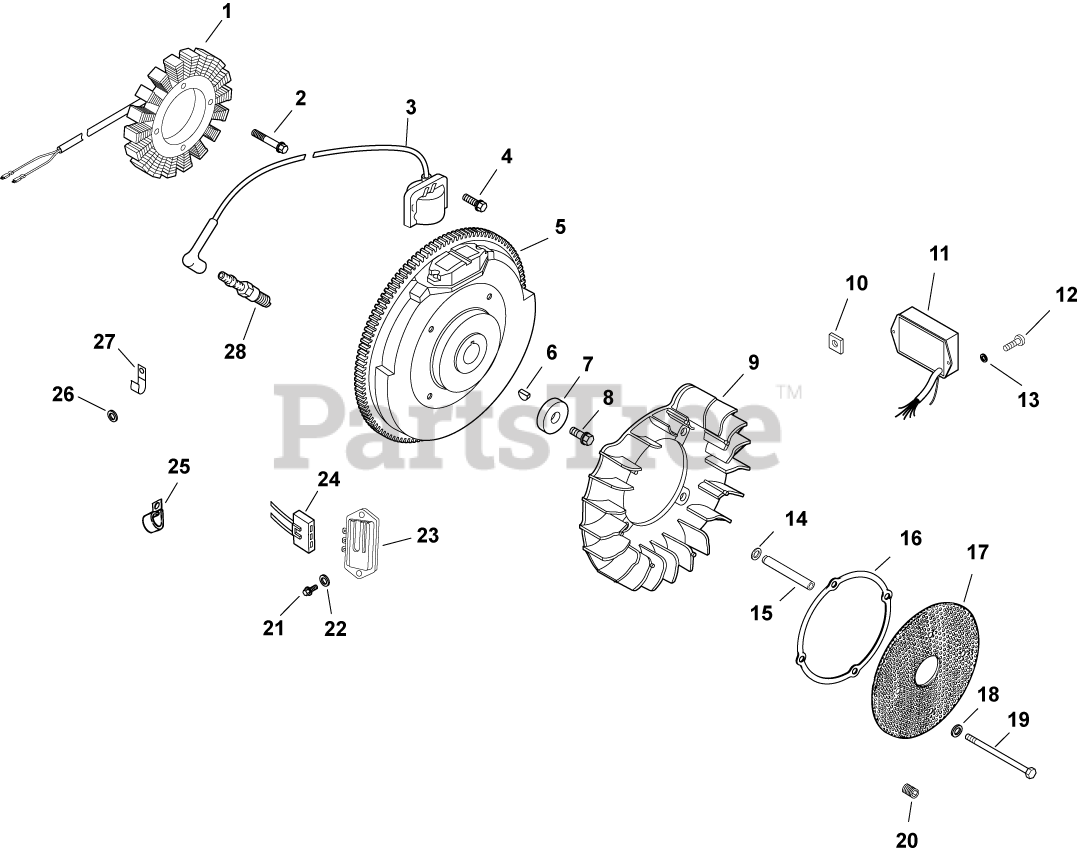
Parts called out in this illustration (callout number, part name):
1	KIT, 15 / 20 AMP STATOR
2	SCREW, M5X0.8X25 - (#25086402S)
3	MODULE, IGNITION
4	SCREW, FLG THD FRM M5X.8X20-(#25086399S)
5	FLYWHEEL ASSEMBLY-USE 24 025 58-S
6	KEY, 3/16" X 5/8"
7	WASHER, FLAT 13/32"
8	SCREW, FLG M10X1.5X45 - (#25086361S)
9	FAN USE 24 755 253-S
10	NUT, PLASTIC
11	MODULE, SPEED ADVANCE -USE 24 755 162-S
12	SCREW, PHL HD #11-16X1/2"
13	WASHER, FLAT 7/32"
14	WASHER, SPRING 10 MM
16	RING, SUPPORT USE 25 141 08-S
17	SCREEN, GRASS
18	WASHER, FLAT 1/4" (O.D. 5/8")
19	SCREW, SOCKET TRUSS HD CAP
20	SCREW, SKT SET #10-24X1/4"
21	SCREW, PHL HD #11-16X7/8"
22	WASHER, FLAT 3/16"
23	REG/RECT-15 AMP (KM)-USE 41 403 10-S
24	CONNECTOR, BODY (KM)-USE 25 155 41-S
25	CLIP, TUBE & WIRING (KM)
26	WASHER, FLAT 1/4" (O.D. 1/2")
27	CLIP, CABLE
28	PLUG, SPARK (PRO SERIES)
2402552-S	FLYWHEEL ASSEMBLY (LW)-USE 24 025 58-S
2458452-S	MODULE, SPARK ADV -USE 24 584 89-S
